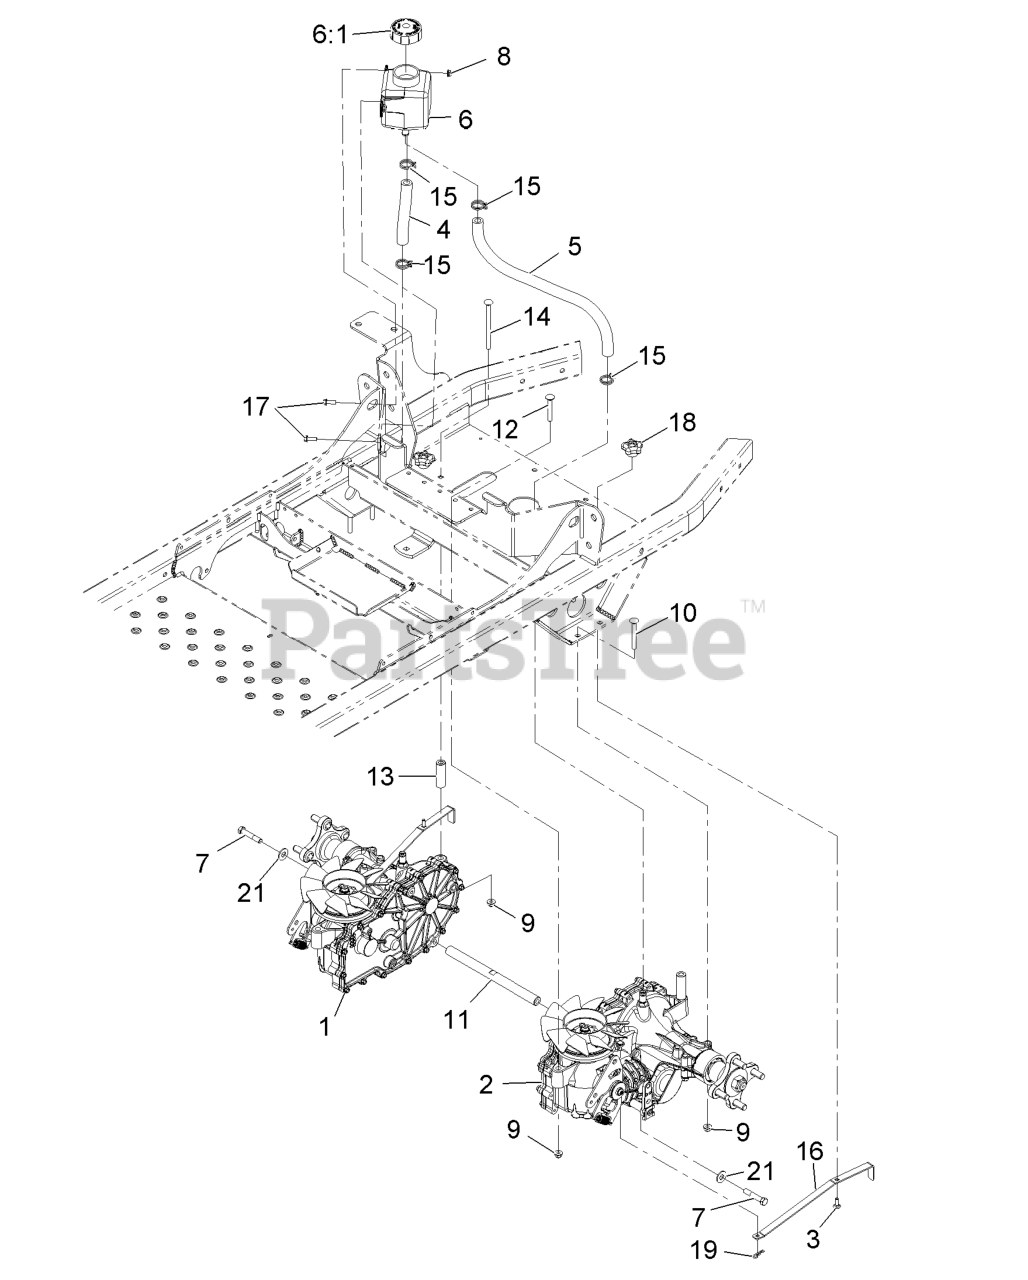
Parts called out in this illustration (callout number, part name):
1	TRANSAXLE ASM
2	TRANSAXLE ASM
3	BOLT-CARR
4	HOSE-HYDRAULIC
5	HOSE-HYDRAULIC
6	TANK-HYD
6:1	CAP-RESERVOIR, HYD
7	SCREW-HH W/LOCTITE
9	NUT-HF, NI
10	SCREW-CARR
11	SHAFT-TRANSAXLE SPACER
12	BOLT-CARR
13	SPACER-HYDRO
14	Bolt-Carriage 5/16-18 X 1 1/4
15	CLAMP-HOSE
16	ARM-BYPASS, HYDRO
17	SCREW-HWH
18	KNOB-HANDLE
19	PIN-COTTER
21	WASHER-FLAT
